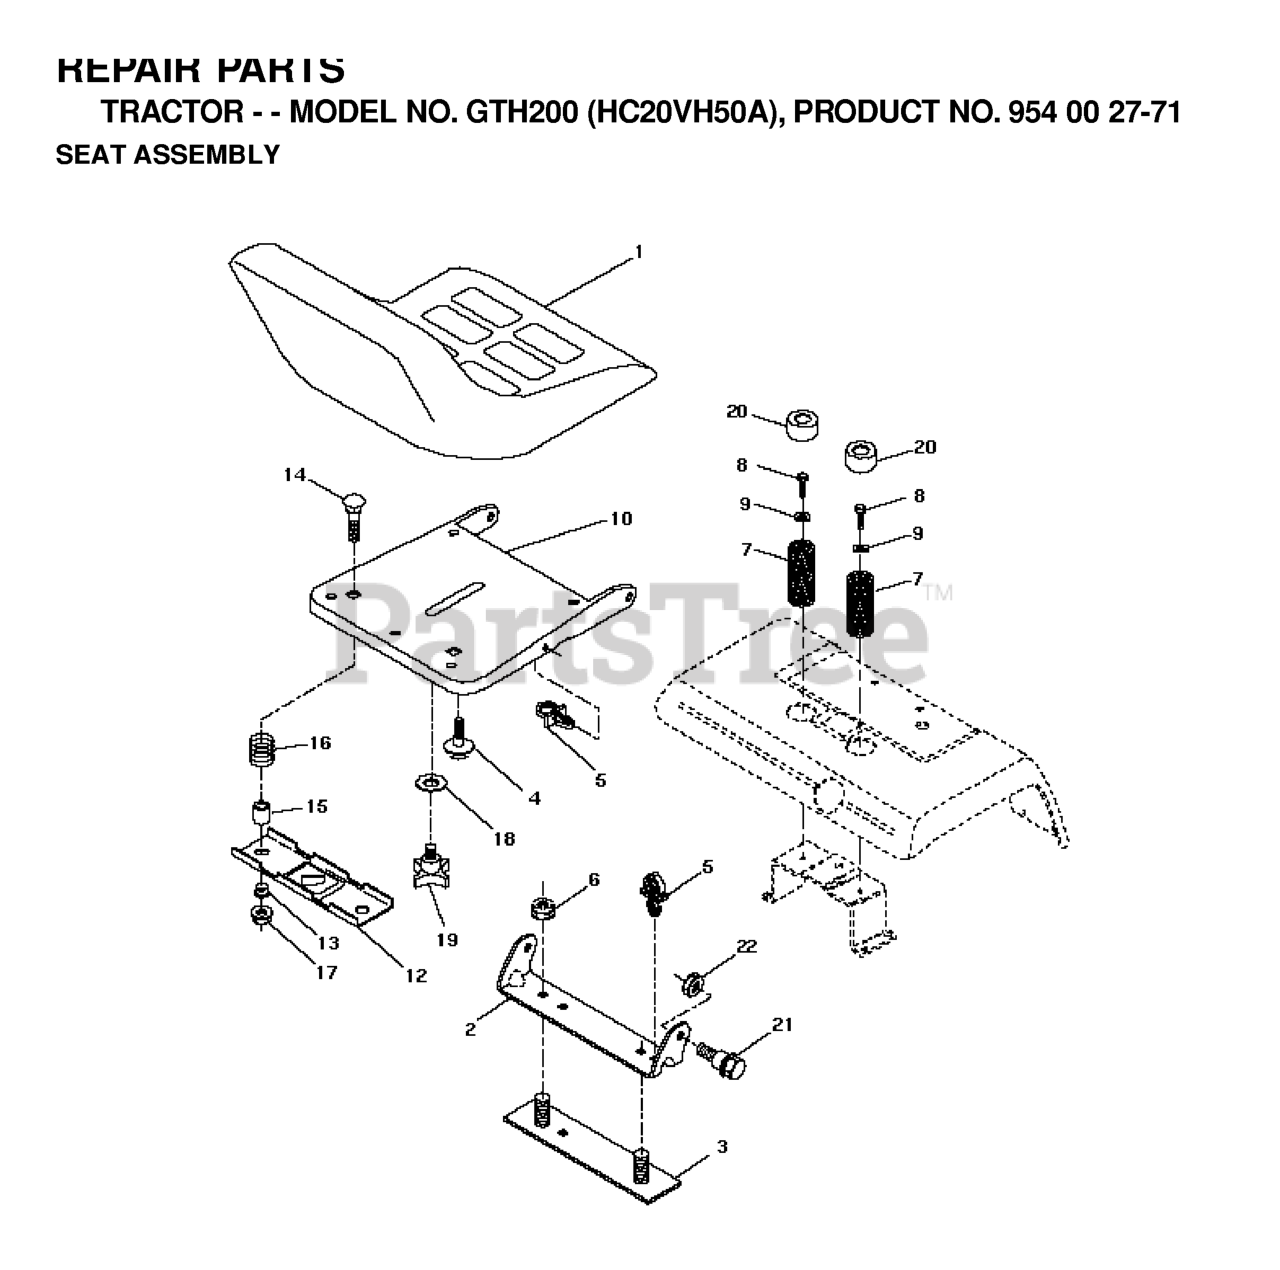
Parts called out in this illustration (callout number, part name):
1	SEAT
2	SEAT PIVOT BRKT
3	STRAP
4	BOLT,SHOULD
6	NUT
7	SPRING COMPRESSION
8	Screw 5/16-18 x 1/2 Hex, Self Tapping 5/16-18 x 1/2
9	WASHER
10	SEAT PAN
12	BRKT SWITCH
14	Bolt Rdhd. Sht. Nk 1/4-20 x 1-3/8
15	SPACER SPLIT
16	SPRING COMPRESSED
17	NUT T
19	KNOB 1/2" YT
20	CAP SPRING
21	BOLT.SHOULDER.5/16-18
22	LOCKNUT
